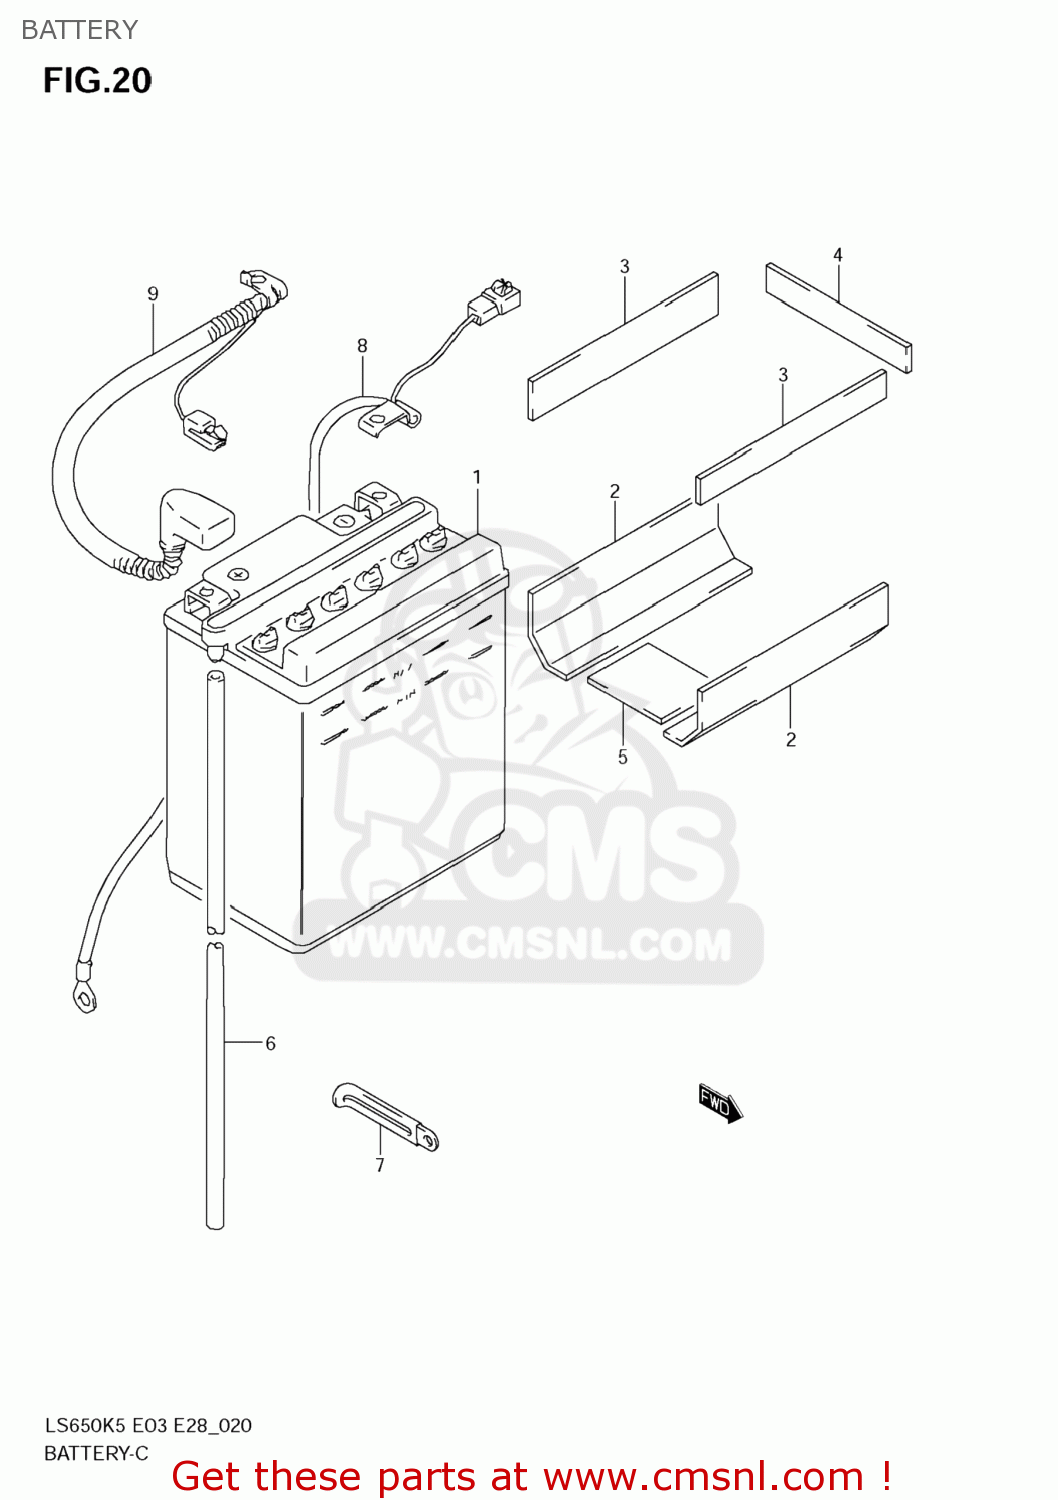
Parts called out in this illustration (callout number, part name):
1	BATTERY(YB14L-B2,12V14.7AH)
2	PROTECTOR(170X95X3.0)
3	PROTECTOR(170X95X3.0)
4	PROTECTOR(20X90)X2
5	PROTECTOR(50X50X5)
6	HOSE,BATTERY EXHAUST(L:780)
7	CLAMP(L:45)
8	WIRE,BATTERY MINUS
9	WIRE,BATTERY PLUS LEAD
